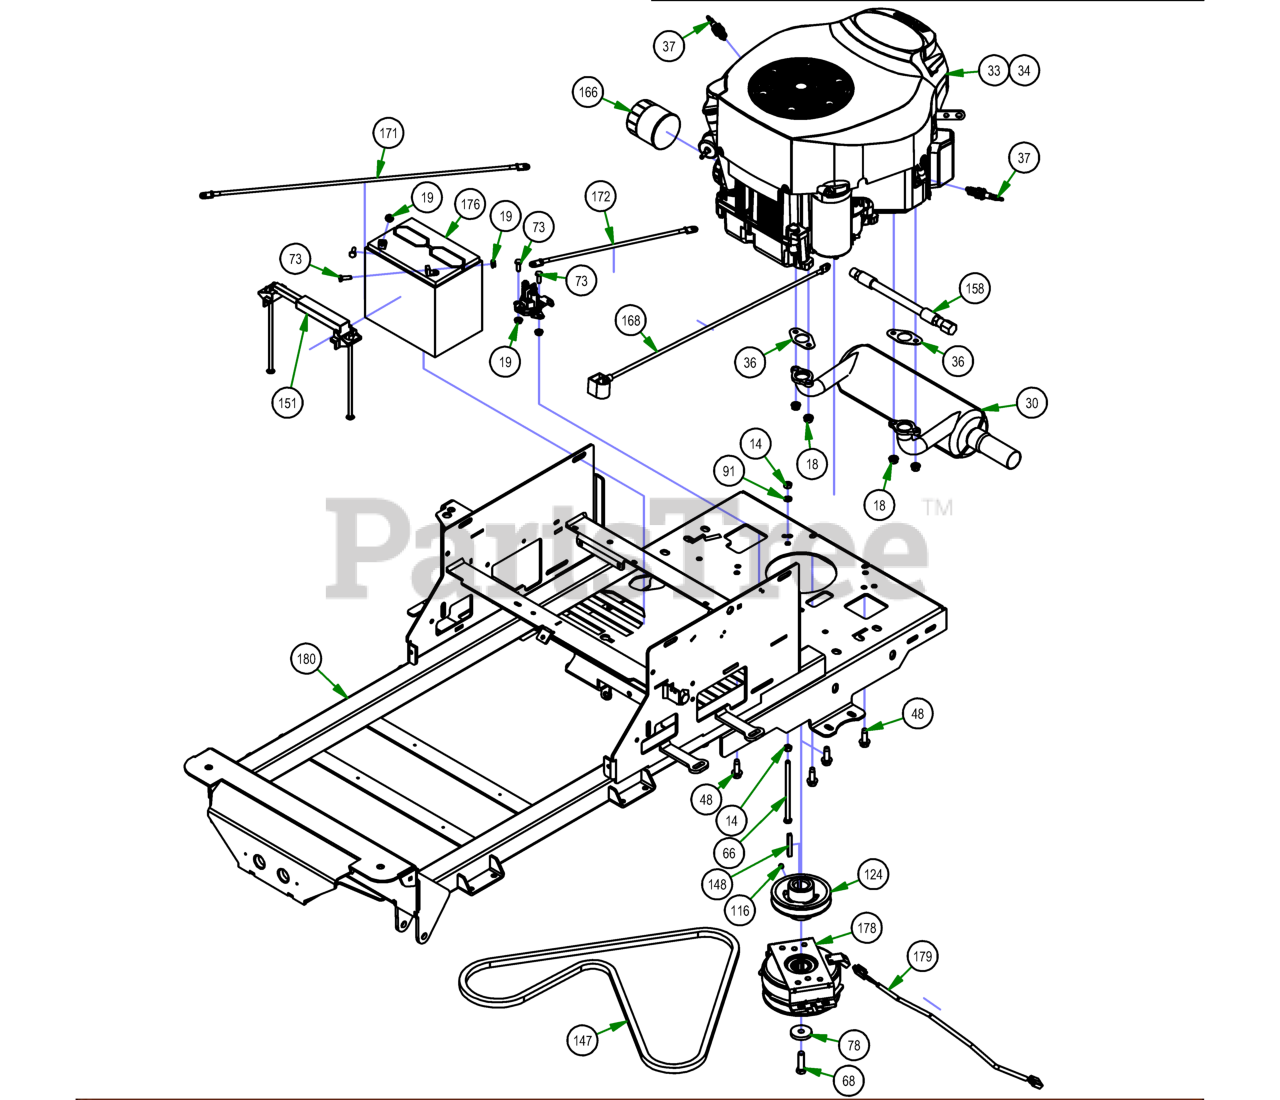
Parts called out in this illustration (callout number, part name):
14	5/16-18 HEX NUT ZINC
18	M8 Nut Connects the 015-1012-00 and the 015-8240-00
19	1/4-20 HEX SERRATED FLANGE NUT HARD/ZINC
30	Kohler Muffler
33	Kohler-2014 ZT 725cc
34	26hp Kohler-2018 ZT-KT745-3088
36	Exhaust Gasket
37	Spark Plug
48	3/8-16 X 1-1/8 HEX WASHER UNSLOT SERRATED (TRI-LOB) TRS ZINC YELLOW
66	5/16-18 X 5-1/2 HEX CAP SCREW (GR.5) ZINC
68	7/16-20 X 1-1/2 HEX CAP SCREW (GR.8) ZINC YELLOW
73	1/4-20 X 3/4 HEX CAP SCREW (GR.5) ZINC
78	CLUTCH WASHER
91	5/16 SPLIT LOCKWASHER ZINC
116	5/16-24 X 1/4 SOCKET SET SCREW (CUP PT) PLAIN
124	4 3/4 Motor Pulley
148	1/4 X 2 SQ MACHINERY KEY 1018 STL PLAIN
151	Hold Down Assembly
158	Oil drain Hose
166	25 HP Kohler Oil Filter ZT?MZ
167	Universal Inline Fuel Filter
168	24 inch Black Cable – MZ/ZT
171	24" Red Battery Cable
172	12 in red battery cable
176	SP-35 Battery
179	Clutch Pigtail
180	2021 ZT Frame - Painted
